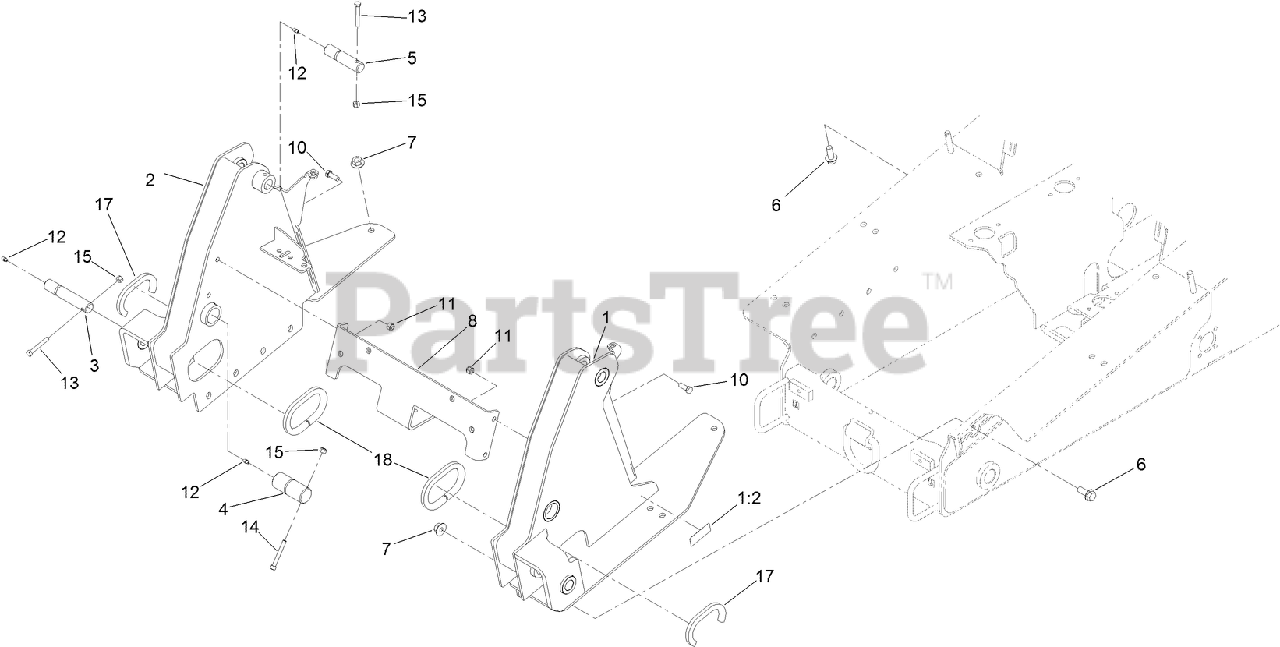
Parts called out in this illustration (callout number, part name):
1	TOWER-FRONT, LH
1:2	DECAL-SURFACE, HOT
2	TOWER, RH
3	PIN-HYD
4	PIN-ARM
5	PIN-LINK
6	SCREW-HHF
7	NUT-LOCK, FLANGE
8	PLATE-CROSS, TOWER
10	SCREW-HH
11	NUT-LOCK, NI
12	FITTING-GREASE
13	SCREW-HH
14	SCREW-HSH
15	NUT-LOCK, NI
17	TRIM-SEAL
18	TRIM-SEAL
